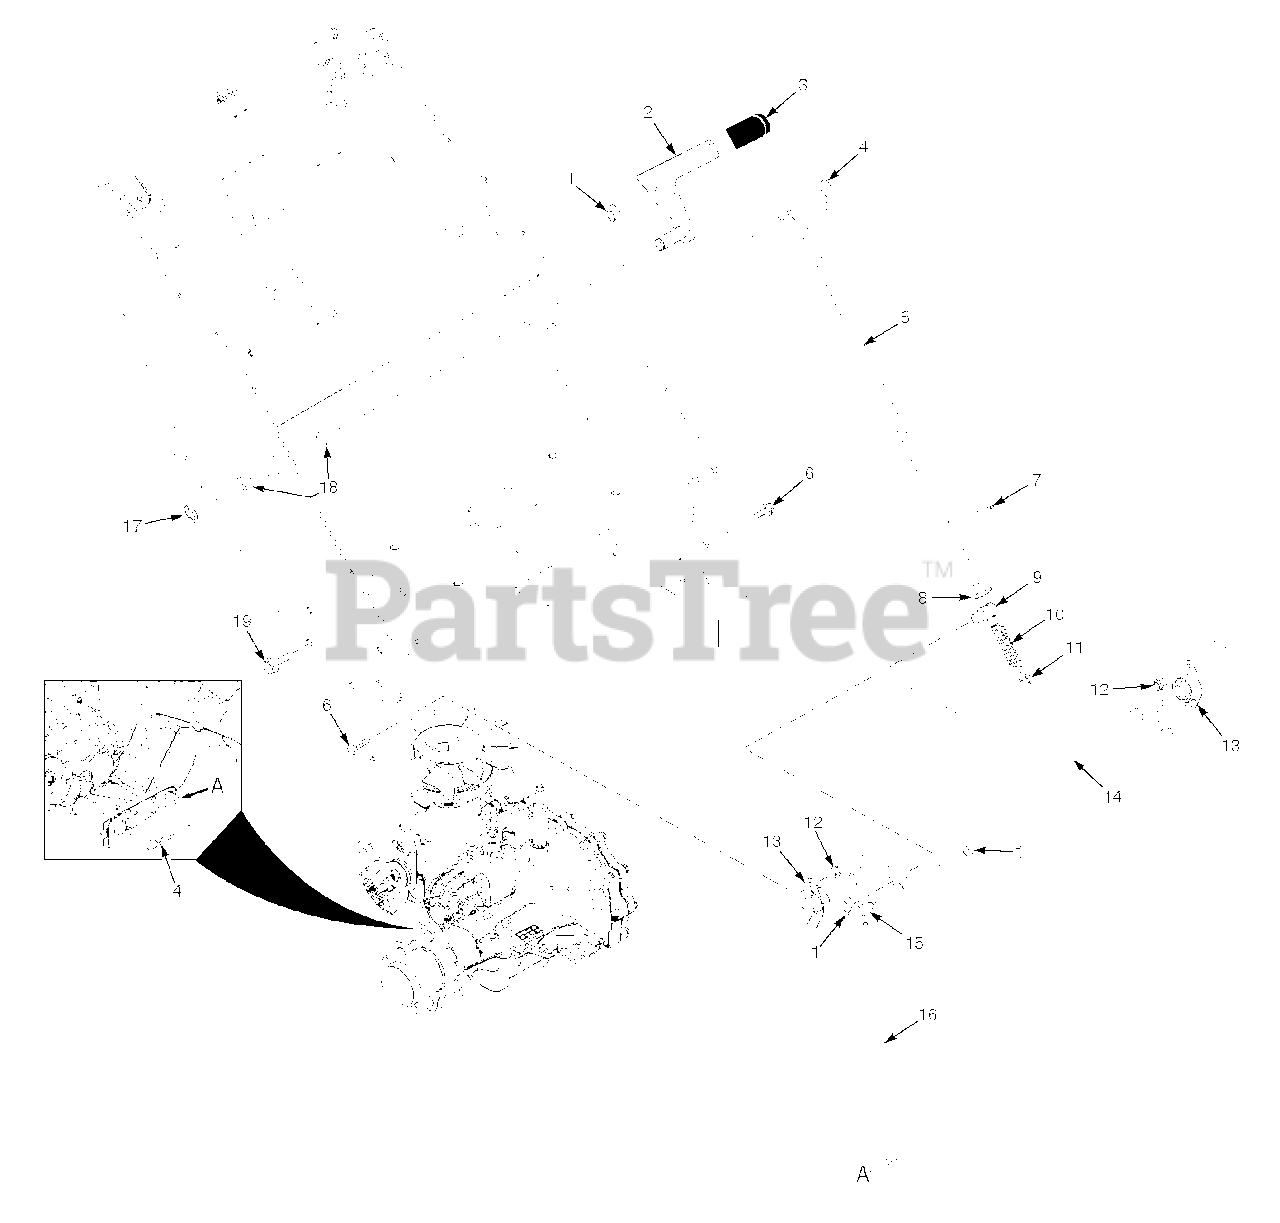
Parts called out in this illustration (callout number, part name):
1	Pin, Rue Cotter 3/8" Dia.
2	Brake Lever w/Grip
3	Grip, Brake Lever
4	Hair Pin, .080 x 1.19"
5	Rod, Brake Linkage
6	Cpscrw, 5/16-18 x 3/4"Serrated Flange HH
7	Cotter Pin, 3/32 x 3/4"
8	Flatwasher, 3/8-.406 x .812 x .065
9	Bushing, Pivot Slide
10	Spring, Brake
11	Nut, Elastic Stop 3/8-24
12	Nut, Elastic Stop 5/16-18
13	Bearing, Self Aligning 5/8" I.D.
14	Weldment, Brake Bellcrank
15	Joint, Swivel
16	Rod, Brake Adjustment
17	Ring, Retaining 5/8" External "E"
18	Bearing
19	Cpscrw, 3/8-16 x 1"Serrated Flange HH
